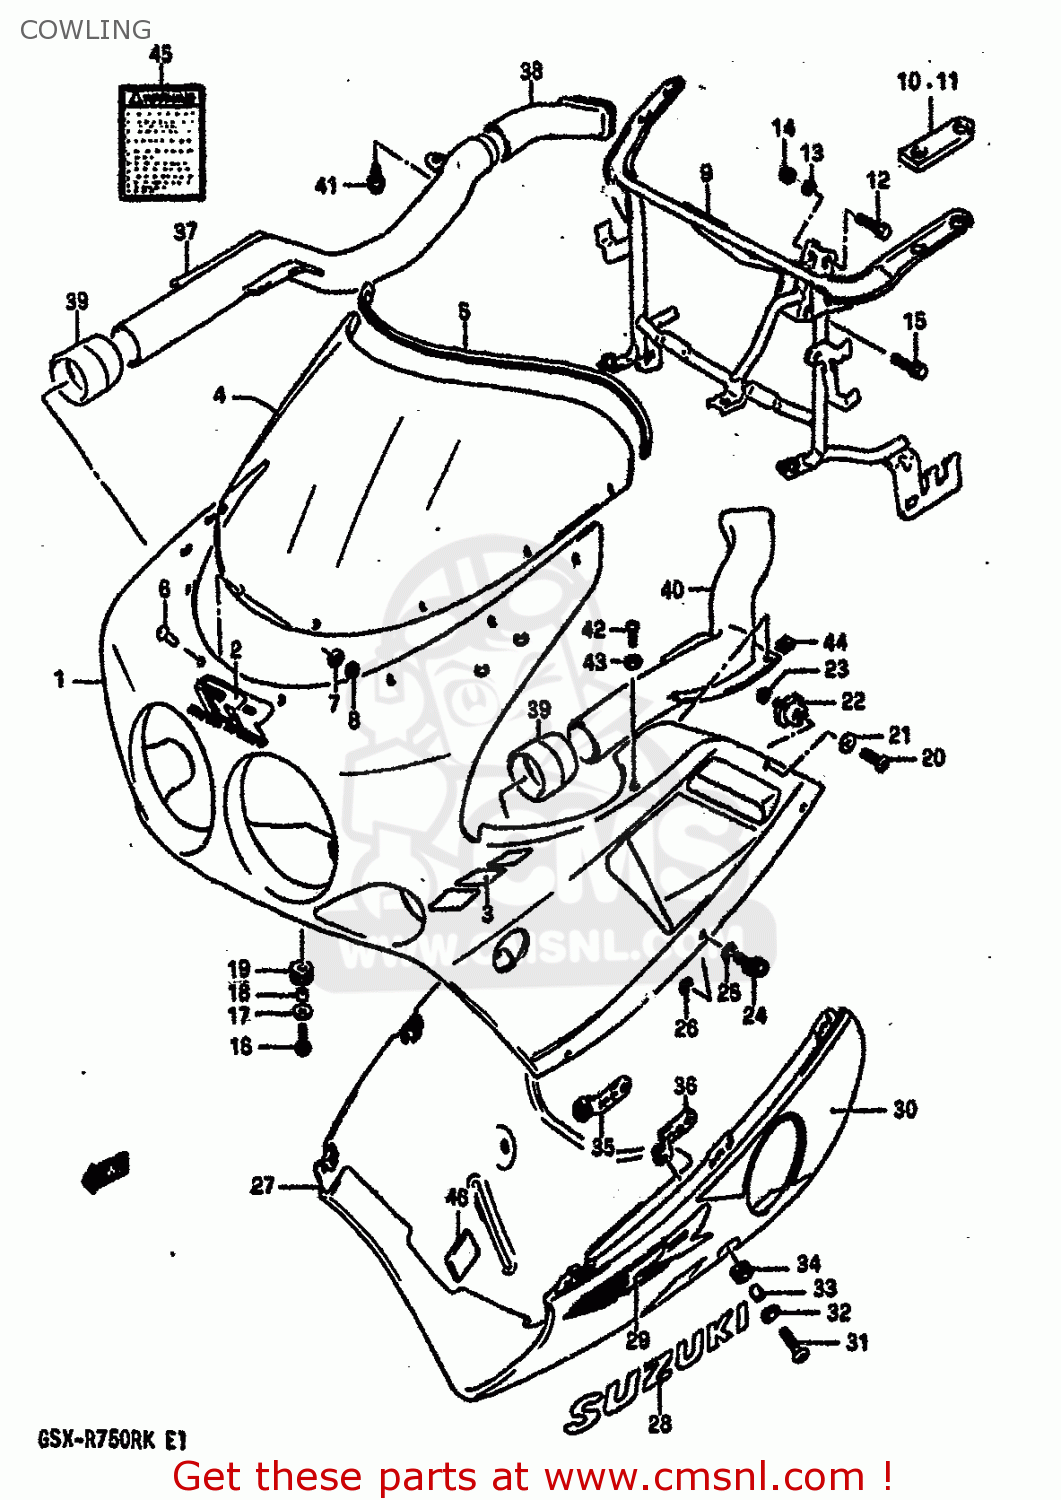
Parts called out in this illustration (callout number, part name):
1	BODY ASSY,COWLING (WHITE/BLUE/BLUE)
2	EMBLEM
3	TAPE SET,COWL UPR
4	WINDSCREEN
5	MOLDING,WINDSCREEN
6	PIN,WINDSCREEN
7	CUSHION
8	NUT
9	BRACE,COWLING
10	CUSHION,MIRROR,RH
11	CUSHION,MIRROR,LH
12	BOLT
13	WASHER,LOCK,8.
14	NUT ,8MM
15	BOLT
16	SCREW(6X20)
17	WASHER(6.5X18X1)
18	SPACER
19	CUSHION
20	SCREW(6X12)
21	WASHER(7X13X0.6)
22	CUSHION,COWLING
23	WASHER,LOCK
24	STUD,COWLING FTG
25	WASHER(7X13X0.6)
26	RETAINER
27	COWLING ASSY,UNDER (WHITE)
28	EMBLEM,"SUZUKI"
29	EMBLEM,COWLING UNDER
30	TAPE SET,COWL UNDER
31	SCREW(6X20)
32	WASHER(6.5X18X1)
33	SPACER
34	CUSHION
35	BRACKET
36	BRACE,COWLING UNDER,LH
37	PIPE,AIR INTAKE FRONT,RH
38	PIPE,AIR INTAKE RR,R
39	JOINT,AIR INTAKE
40	PIPE,AIR INTAKE FRONT,LH
41	BOLT
42	SCREW(5X18)
43	WASHER
44	NUT,HEADLAMP HOUSING,UPPER
45	LABEL (WARNING SCREEN)
46	PROTECTOR,FRAME COVER FR
